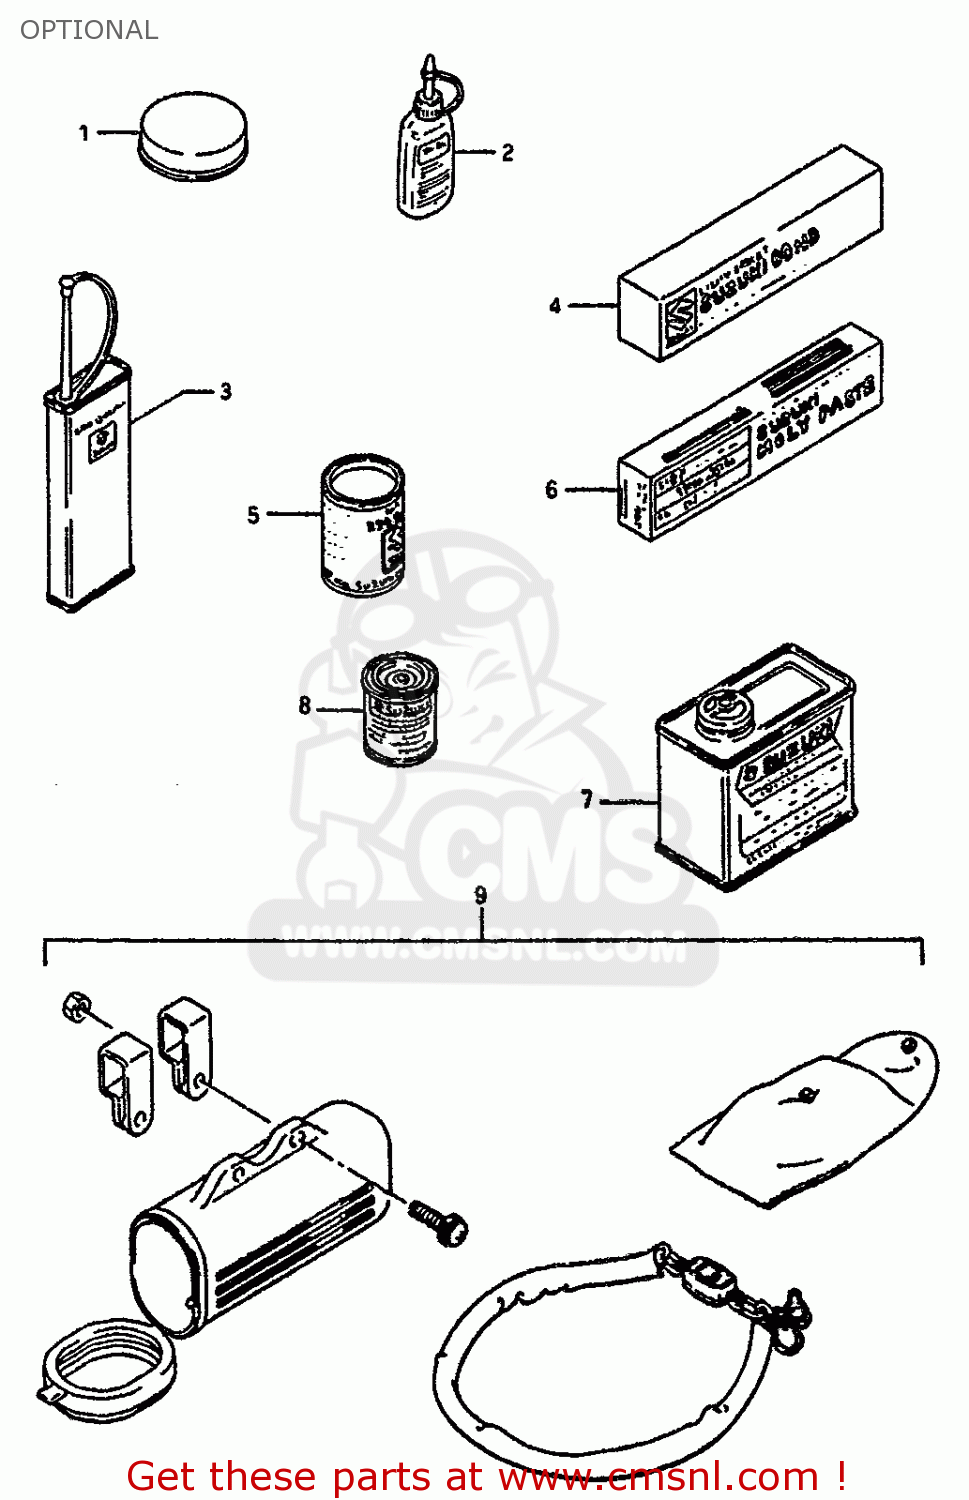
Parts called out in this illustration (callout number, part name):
1	GREASE,PBC FOR BRK PAD 20G
2	THREAD LOCK NO.1342
3	THREAD LOCK NO.1401 CLEAR 200G
4	LIQUID GSKT NO.1207B 100G BLK
5	GREASE(C)EP2 LITHIUM 150G
6	SUZUKI MOLY PASTE
7	PAINT (SPECIAL WHITE)
8	PAINT (SPECIAL WHITE)
9	LOCK SET,CHAIN
